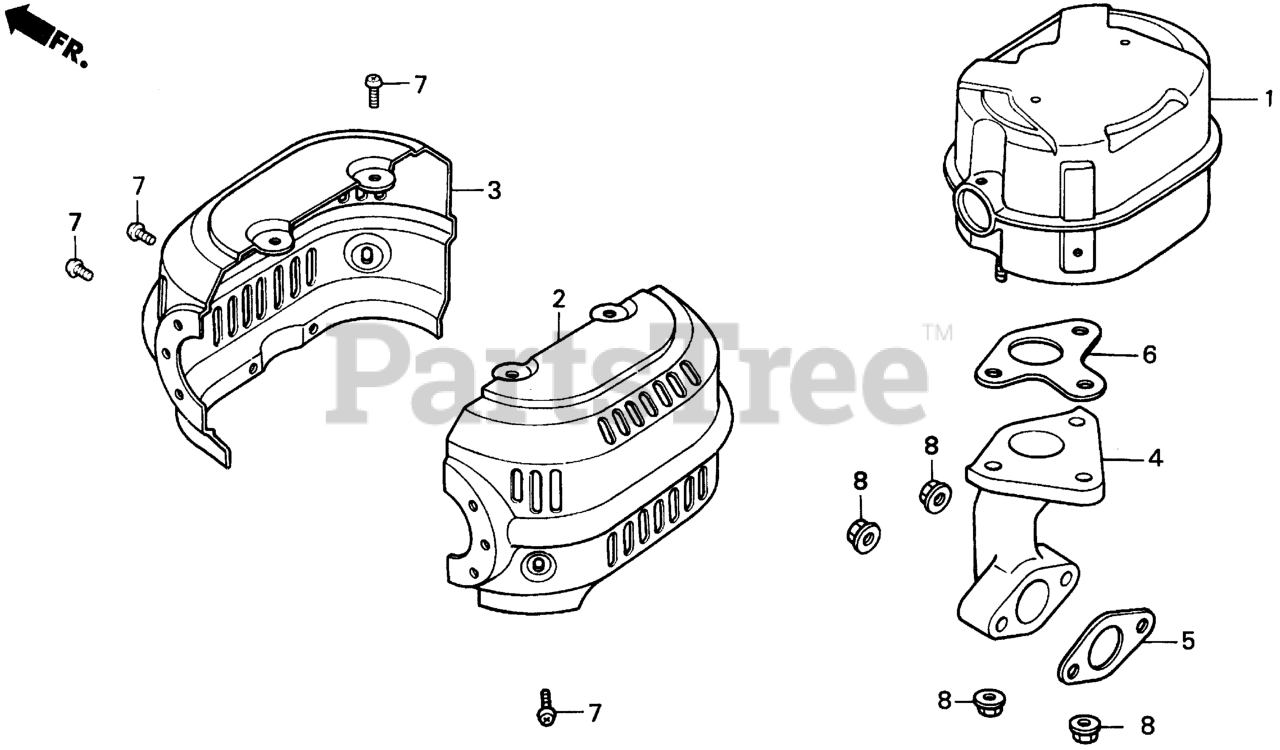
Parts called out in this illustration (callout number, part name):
1	MUFFLER
2	PROTECTOR, R. MUFFLER (ALUMINIZED)
3	PROTECTOR, L. MUFFLER (Honda Code 4049946). (ALUMINIZED)
4	PIPE, EX.
5	GASKET, EX. PIPE Use up to Engine SN 2949254.
5	GASKET, EX. PIPE (WACKER)
6	GASKET, MUFFLER
6	GASKET, MUFFLER (NIPPON LEAKLESS)
7	SCREW, TAPPING (5X8)
8	NUT, FLANGE (8MM)
